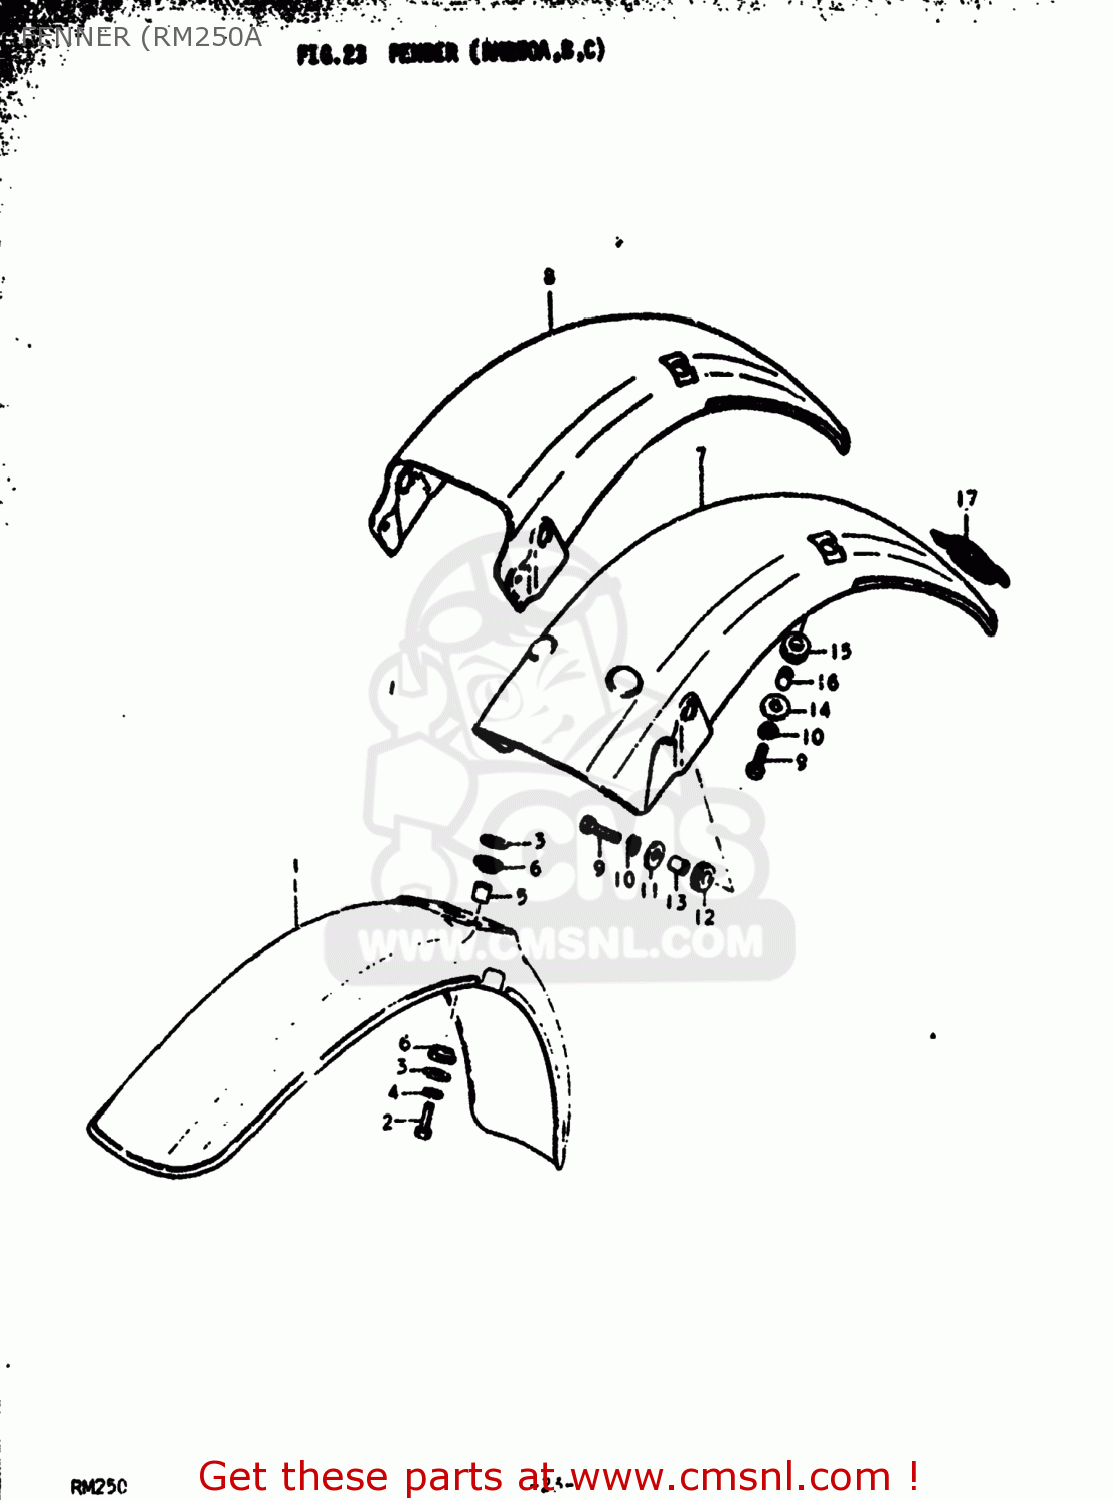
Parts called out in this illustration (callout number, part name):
1	FENDER,FRONT
2	BOLT
3	WASHER (6.5X20X1.2)
4	LOCK WASHER
5	SPACER (6.8X10X10)
6	CUSHION
7	FENDER,REAR
8	FENDER,REAR
9	BOLT
10	LOCK WASHER
11	WASHER (6.5X20X1.2)
12	CUSHION
13	SPACER(6.1X9X7.5)
14	WASHER (6.5X24X1.6)
15	CUSHION
16	SPACER
